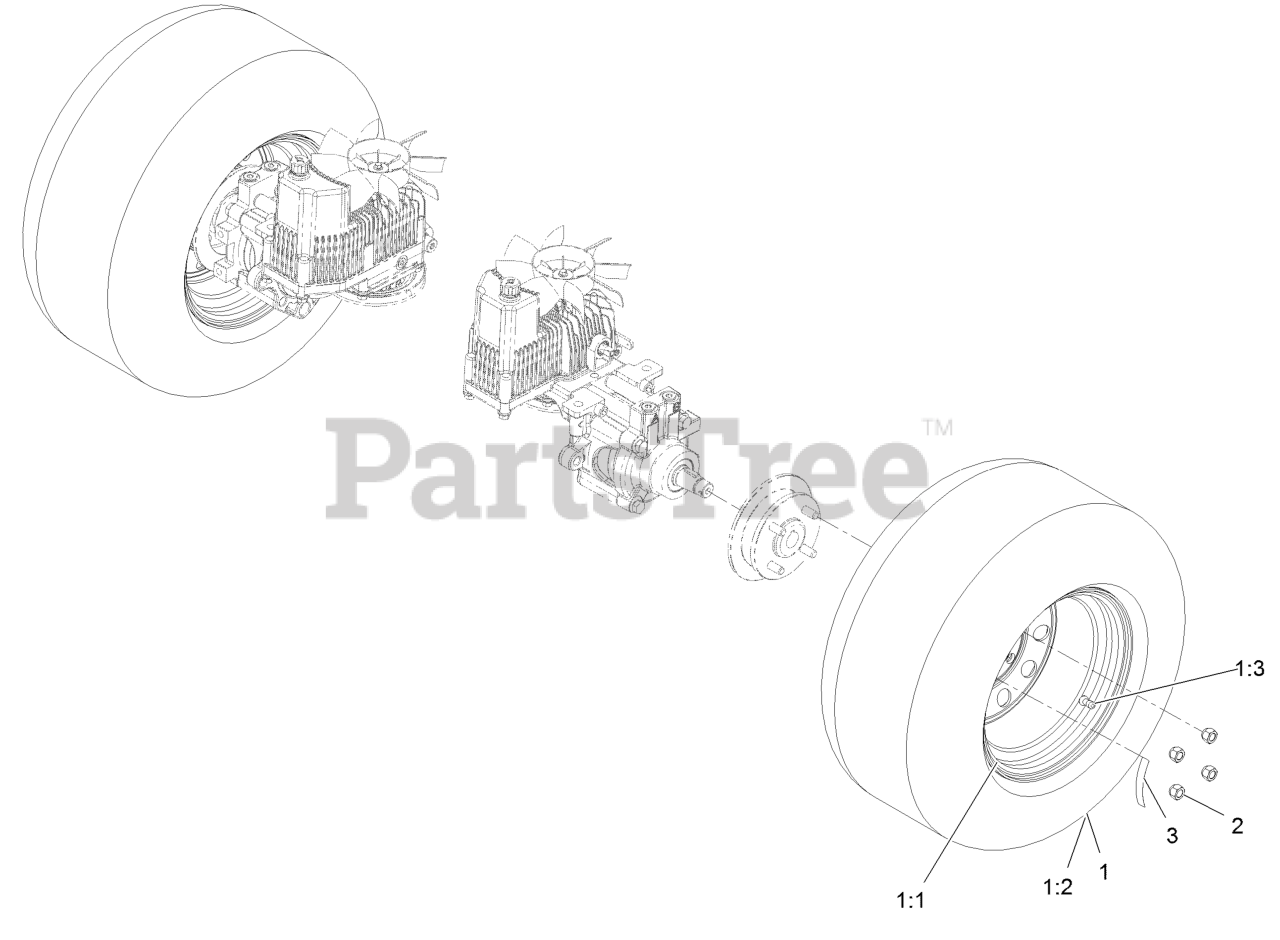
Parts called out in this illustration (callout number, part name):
1	Wheel And Tire ASM
1:3	Stem-Valve
2	Nut-Lug 1/2-20
3	Decal-Torque, Wheel Hub Lug
